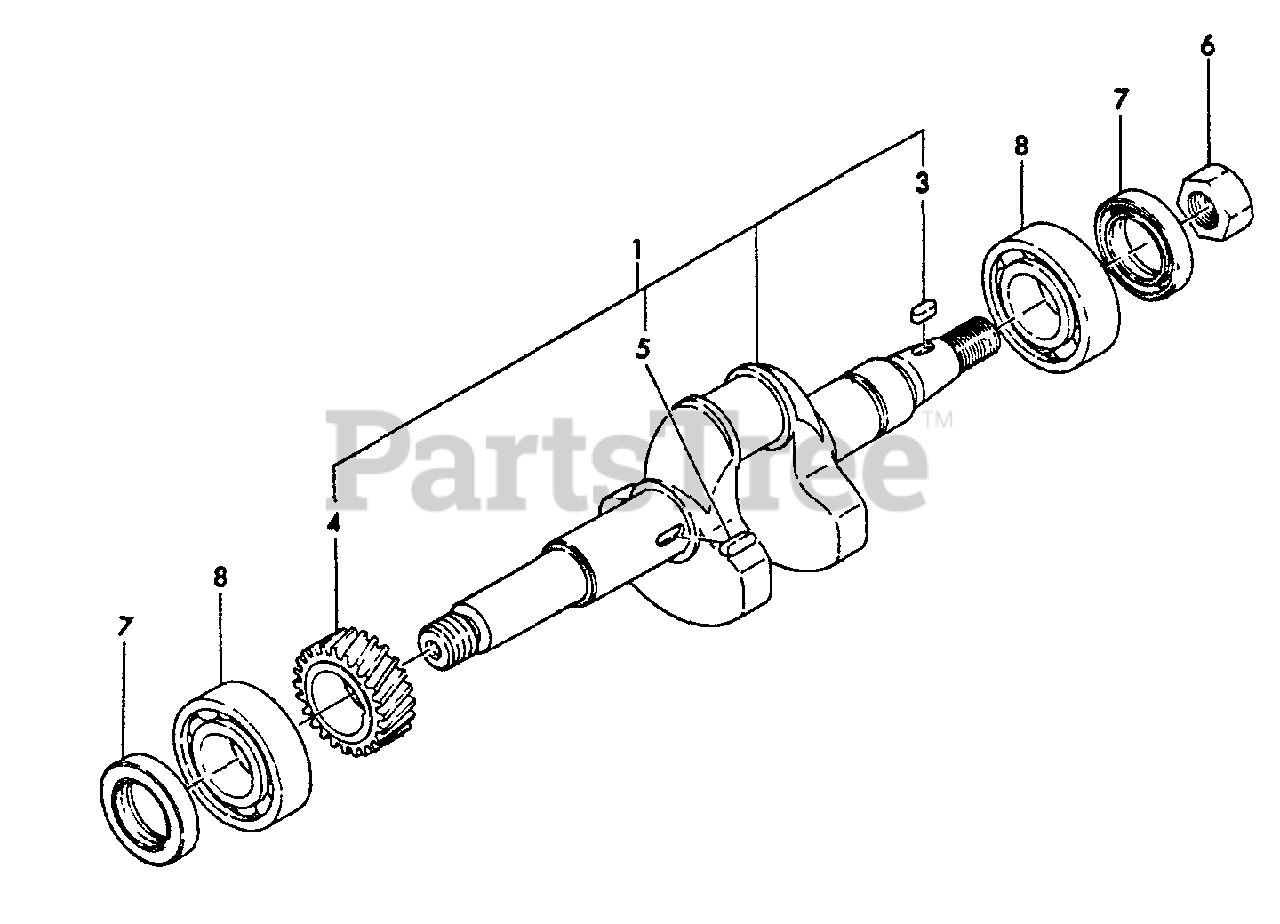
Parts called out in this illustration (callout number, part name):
1	CRANKSHAFT ASSY
3	KEY - 4X10
4	GEAR, CRANKSHAFT
5	KEY - 4X12
6	NUT - 14
7	SEAL, OIL
8	BEARING, BALL - 6205C3
